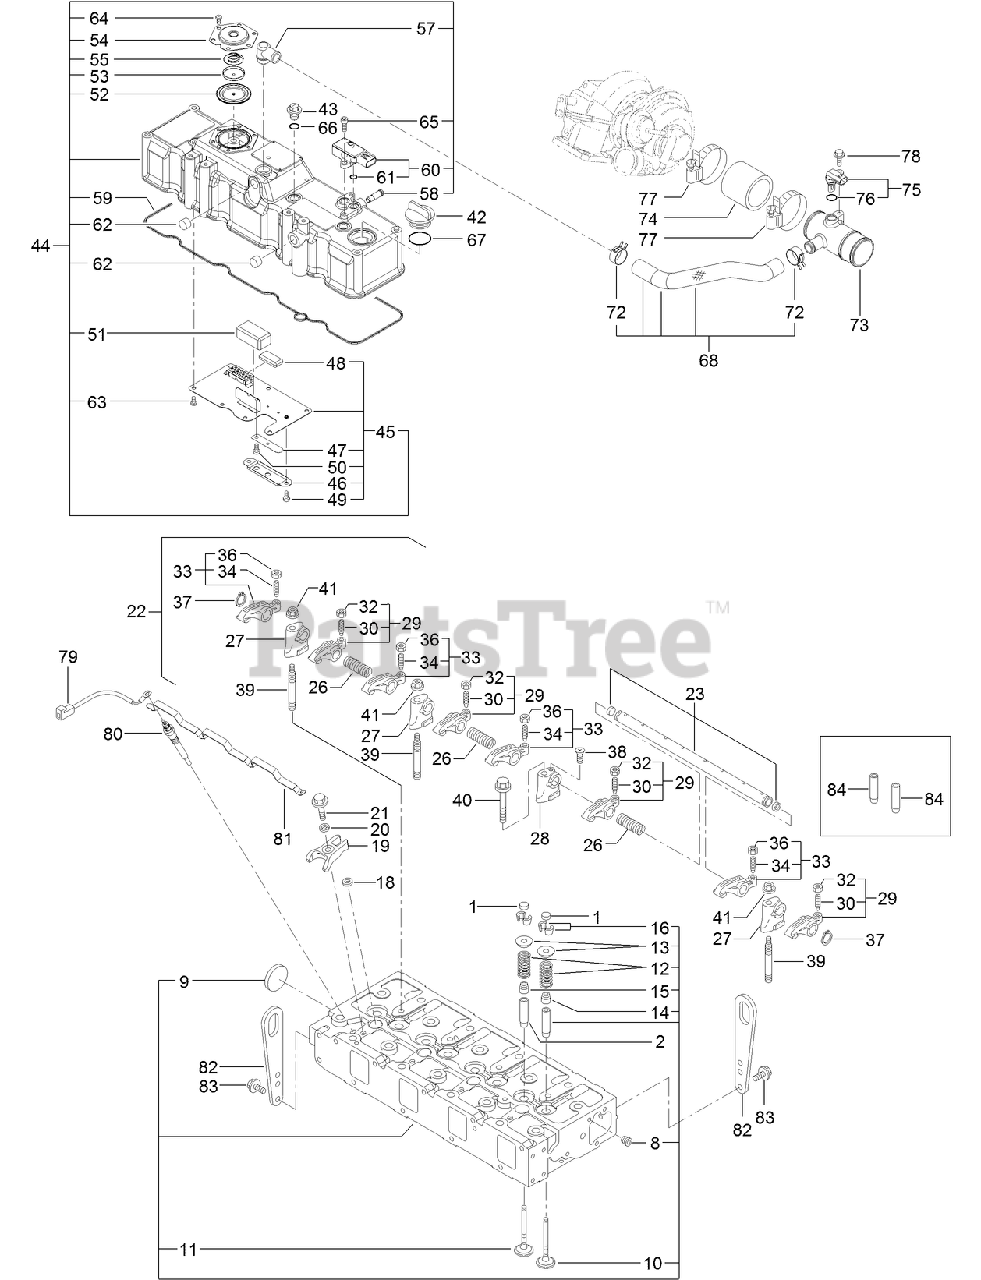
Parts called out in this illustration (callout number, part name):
1	CAP-VALVE
2	CYLINDER HEAD ASM
10	VALVE-INTAKE
11	VALVE-EXHAUST
12	SPRING-VALVE
13	RETAINER-SPRING
14	SEAL-STEM, VALVE
15	SEAL-STEM, VALVE
16	PIN-COTTER
18	GASKET-INJECTOR
19	RETAINER-INJECTOR
20	WASHER-INJECTOR
22	ARM SUPPORT ASM
23	ROCKER SHAFT ASM
26	SPRING-ARM, ROCKER
27	SUPPORT-ARM, ROCKER
28	SUPPORT-ARM, ROCKER
29	ARM-ROCKER
30	SCREW-ADJUST, VALVE
33	ARM-ROCKER
34	SCREW-ADJUST, VALVE
42	COVER-FILLER
44	CYLINDER HEAD COVER ASM
45	PLATE-BAFFLE
46	COVER-PLATE, SPRING
47	SPRING-PLATE
48	BAFFLE-BREATHER
51	BAFFLE-BREATHER
52	DIAPHRAGM
54	PLATE-BREATHER
55	SPRING-DIAPHRAGM
59	GASKET-COVER, HEAD
60	SENSOR-PRESSURE
61	O RING-SENSOR, PRESSURE
66	O-RING
67	O-RING
68	BREATHER HOSE ASM
72	CLIP-HOSE
73	BREATHER JOINT
74	HOSE-INTAKE
75	SENSOR-TEMP, AIR
76	O-RING
77	CLAMP-HOSE
79	HARNESS-WIRE
80	PLUG-GLOW
81	CONNECTOR-PLUG, GLOW
82	LIFTER
84	GUIDE-VALVE
